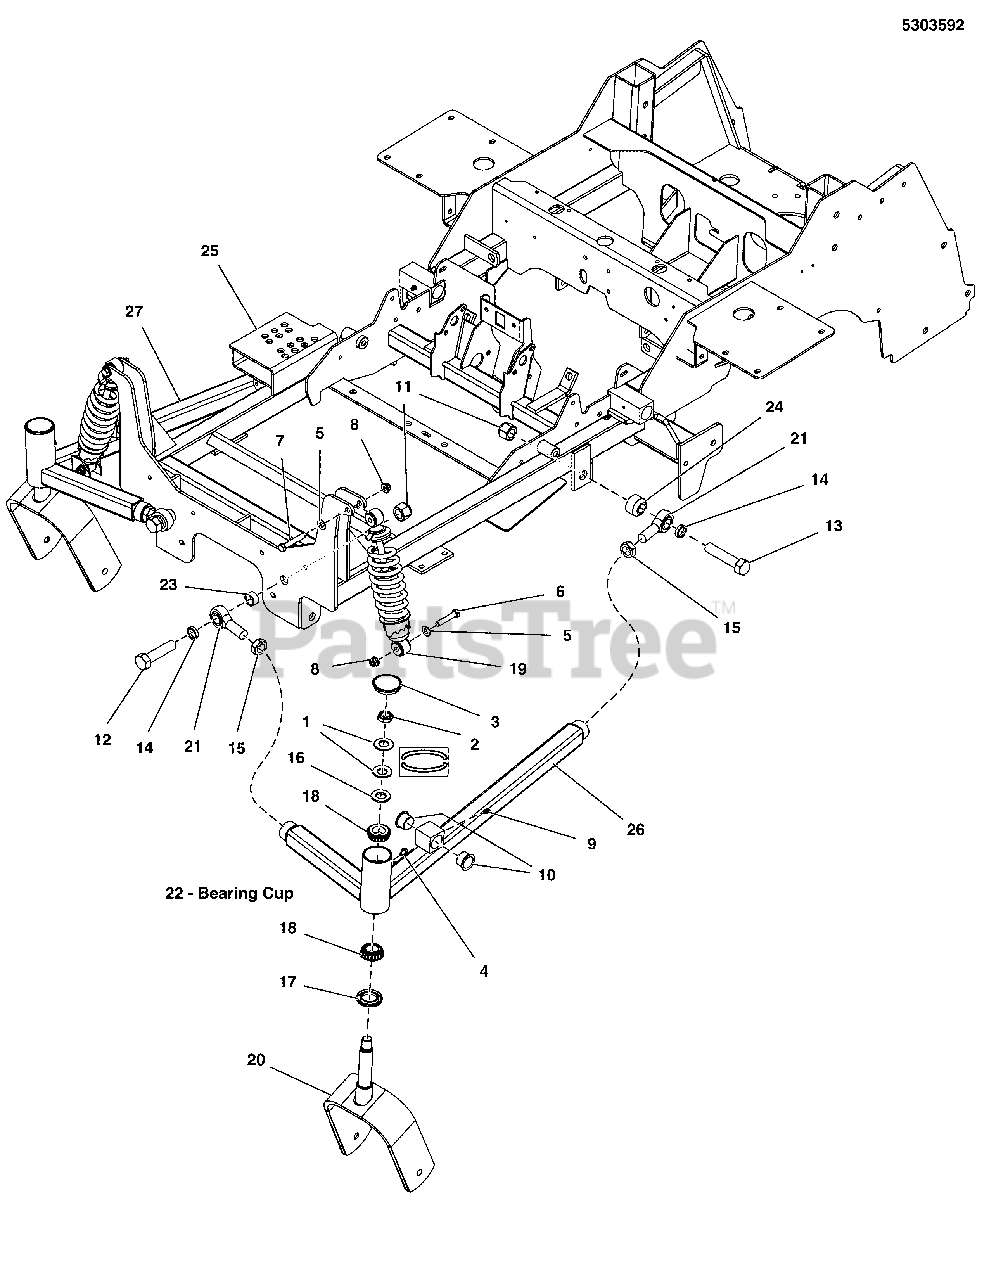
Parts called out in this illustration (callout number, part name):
1	WASHER, BELLEVILLE - 1.500 X .755
2	NUT, 3/4-16, HEX JAM NYLON LOCK
3	CAP, LOW PROFILE, STEEL
4	BOLT, 1/4-28 X 1/2, GD5 YZ
5	WASHER, 3/8 SAE
6	BOLT, 3/8-16 X 2 GD5 YZ
7	BOLT, 3/8-16 X 2-1/4 GD5 YZ
8	NUT, 3/8-16 HEX NYLOCK FLANGE
9	GREASE FITTING, 1/4-28 STRAIGHT
10	BUSHING, 1.00 X 1.13 X .75, PLASTIC
11	NUT, 3/4-16 HEX NYLON LOCK
12	BOLT-3/4-16 X 3 YZ GD8
13	BOLT, 3/4-16 X 3-1/2 YZ GD8
14	SPACER, .76 X 1.00 X .25
15	NUT, 3/4-16 HEX JAM
16	WASHER, 3/4" SAE
17	SEAL, GREASE
18	BEARING, TAPERED ROLLER, 1
19	SHOCK / SPRING ASSEMBLY, OE22375
20	WELD, CASTER YOKE - ORG
21	BALL JOINT, 3/4-16, MALE
22	BEARING, CUP (SV)
23	SPACER, .76 X 1.00 X .50, CZ
24	SPACER, .75 X 1.50 X 1.00, CZ
25	WELD, MAIN FRAME, COBALT - ORG
26	WELD, FRONT A-ARM, LH - ORG
27	WELD, FRONT A-ARM, RH - ORG
